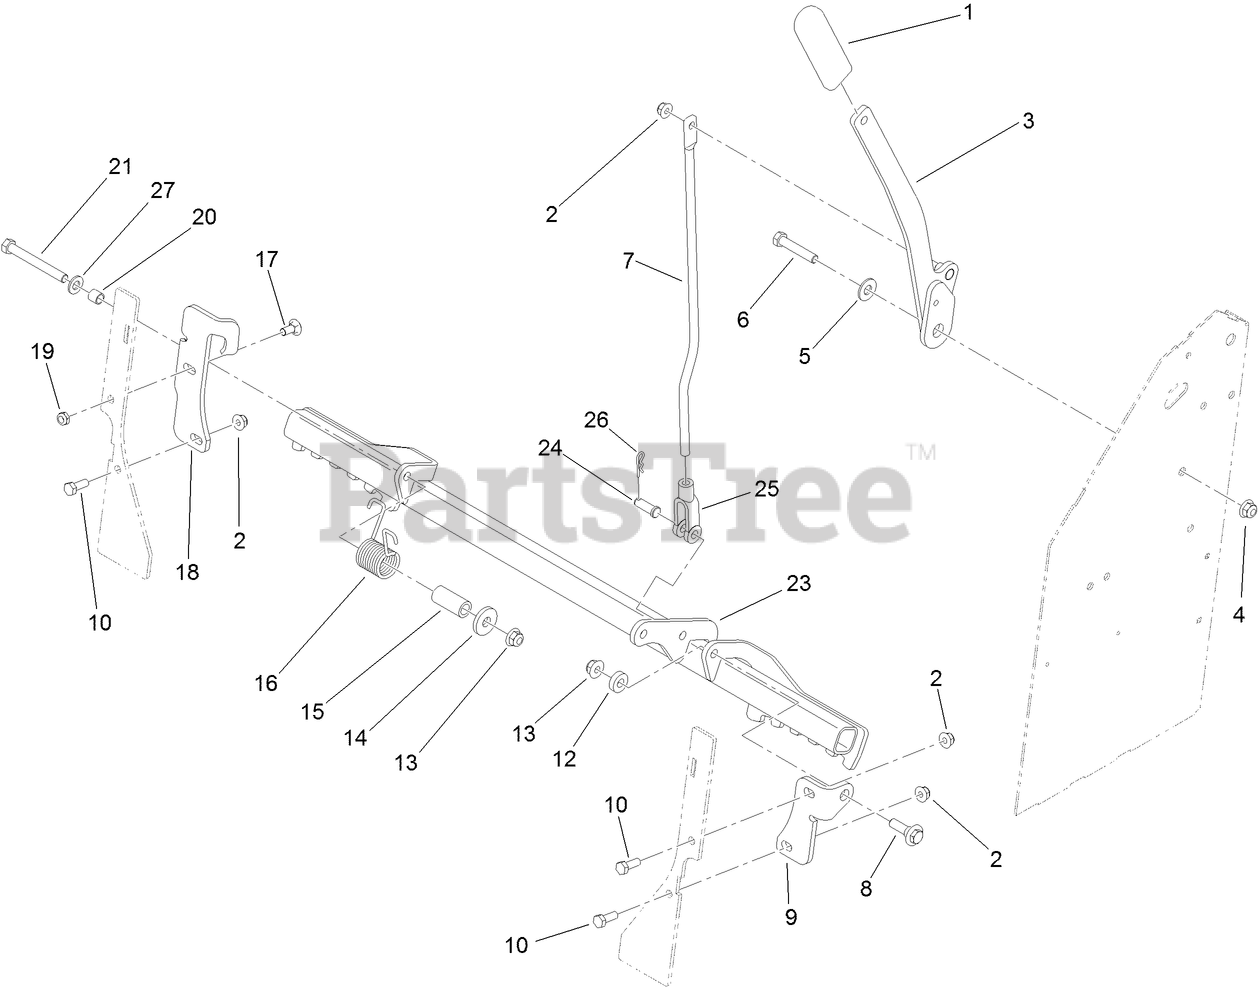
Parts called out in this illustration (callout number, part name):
1	GRIP-LEVER
2	NUT-HF, NI
3	HANDLE-BRAKE
4	NUT-HF, NI
5	WASHER-FLAT
6	SCREW-HH
7	ROD-LINK, BRAKE
8	SCREW-SHOULDER, HWH
9	BRACKET-BRAKE MOUNT, LH
10	SCREW-HH
12	SPACER
13	NUT-HF, NI
14	WASHER
15	SPACER
16	SPRING-TORSION
17	BOLT-CARR
18	BRACKET-BRAKE MOUNT, RH
19	NUT-LOCK, NI
20	SPACER
21	SCREW-HH
23	BAR-BRAKE
24	PIN-CLEVIS
25	YOKE-LINKAGE, BRAKE
26	PIN-COTTER
27	WASHER-FLAT
